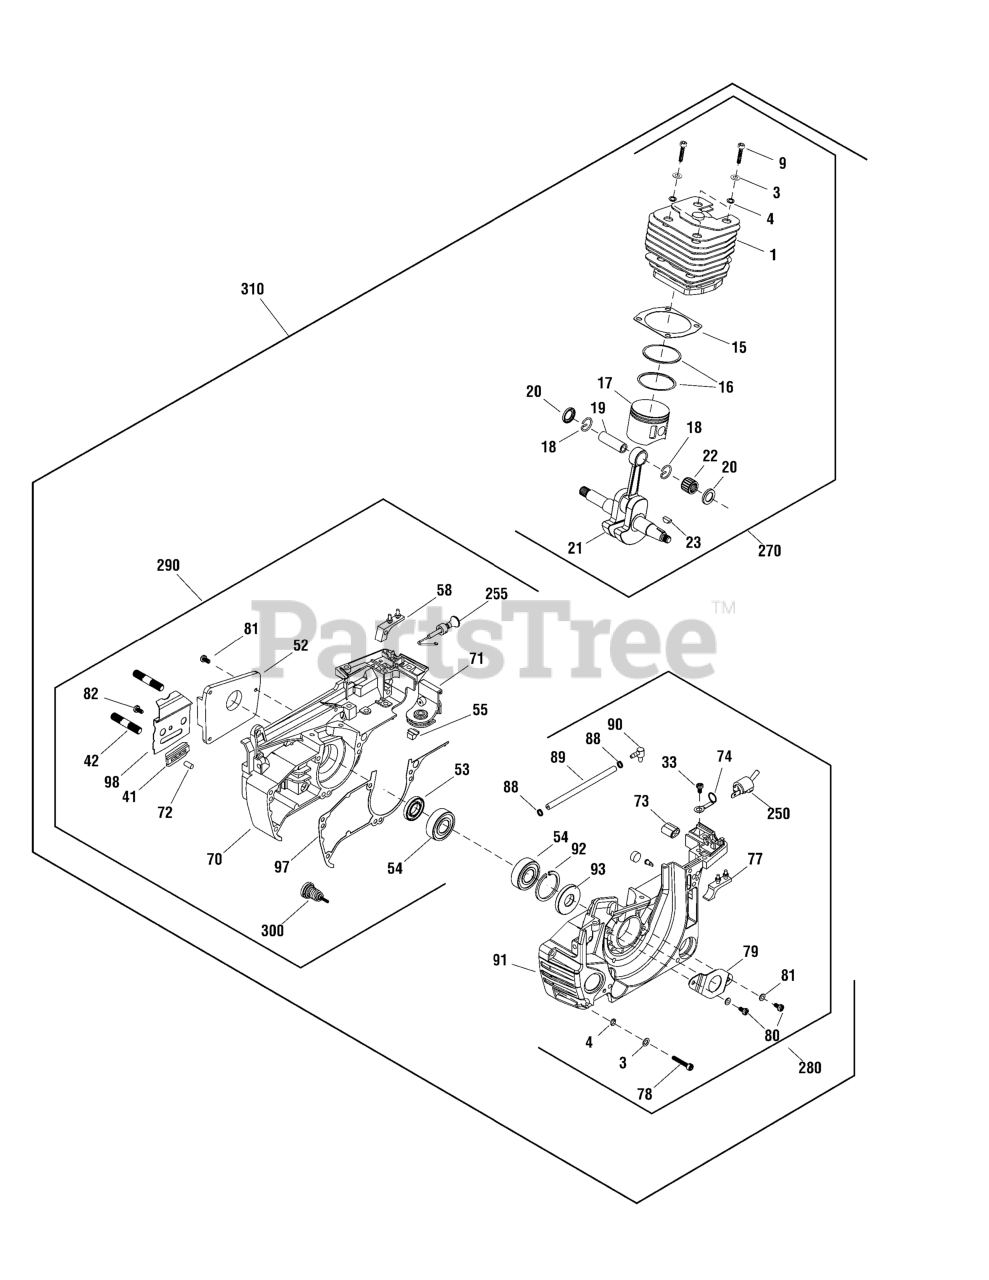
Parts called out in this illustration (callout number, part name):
1	CYLINDER
15	SEALING PLATE, Cylinder
16	PISTON RING
17	PISTON
18	CIRCLIP, Piston
19	PIN, Piston
20	NEEDLE BEARING RING
21	CRANK SHAFT
41	BLOCK, Chain Guide
52	COVER PLATE
55	CUSHION BLOCK
58	SHOCK BLOCK, RH
70	CASE, RH
71	DUST PLATE
73	GUIDE SLEEVE
74	EARTHING STRIP
77	SHOCK BLOCK, LH
79	OIL SHIELD
88	CIRCLIP, Suction Tube
90	SUCTION JET
91	CASE, LH
97	CASE BODY SEALING PLATE
98	DAMPER
250	STARTER SWITCH ASSEMBLY
255	CHOKE ASSEMBLY
270	CYLINDER & PISTON ASSEMBLY
280	CHASSIS ASSEMBLY, LH
290	CHASSIS ASSEMBLY, RH
300	SPRING BASE ASSEMBLY
310	ENGINE, 45cc, Complete
